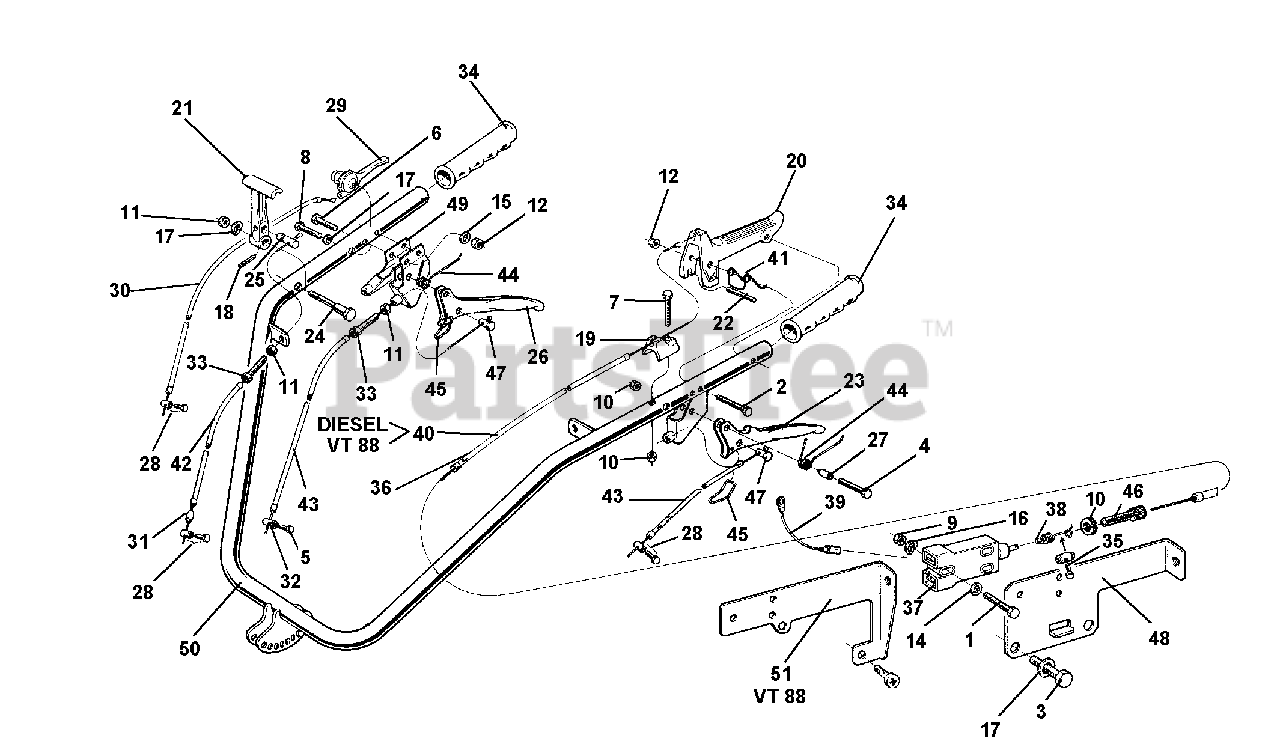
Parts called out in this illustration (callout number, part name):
1	SCREW TE M4 X 25
2	SCREW TE M6 X 45
3	SCREW TE M8 X 12
4	SCREW M6 X 25
5	SCREW TE M6 X 16
6	SCREW M6 X 40
7	SCREW M6 X 35
8	SCREW TE M8 X 40
12	NUT, SELF LOCKING M6
13	NUT, SELF LOCKING M8
14	FLAT WASHER 4.3
15	WASHER, LOCK 6.4
16	LOCK WASHER B 4.3
17	WASHER, LOCK B 8.4
18	PIN, LOCKING 4 X 20
19	SHEATH STOP OF MOTOR STOP
20	MOTOR STOP LEVER
21	LEVER DIFFERENTIAL LOCKING
22	LEVER STOP FOR MOTOR STOP
23	CLUTCH LEVER
25	DRILLED PIN
27	LEVER SPACER
28	CLAMP, CABLE
29	LEVER, ACCELERATOR
30	CABLE & SHEATH, ACCEL. AD114
31	END, SHEATH
32	PIN, CALE CLAMP
33	SCREW, ADJUSTING M8
35	CABLE CLAMP
36	SHEATH CABLE
37	STOP SWITCH
38	SWITCH SPRING
39	SWITCH CABLES
40	SHEATH CABLE
41	MOTOR STOP LEVER SPRING
42	WIRE AND SHEATH L 800
43	SHEATH CABLE
44	LEVER SPRING
46	ADJUSTING SCREW
48	SUPPORT FOR ACME STOP SWITCH
49	COUPLING FOR DOUBLE LEVER
